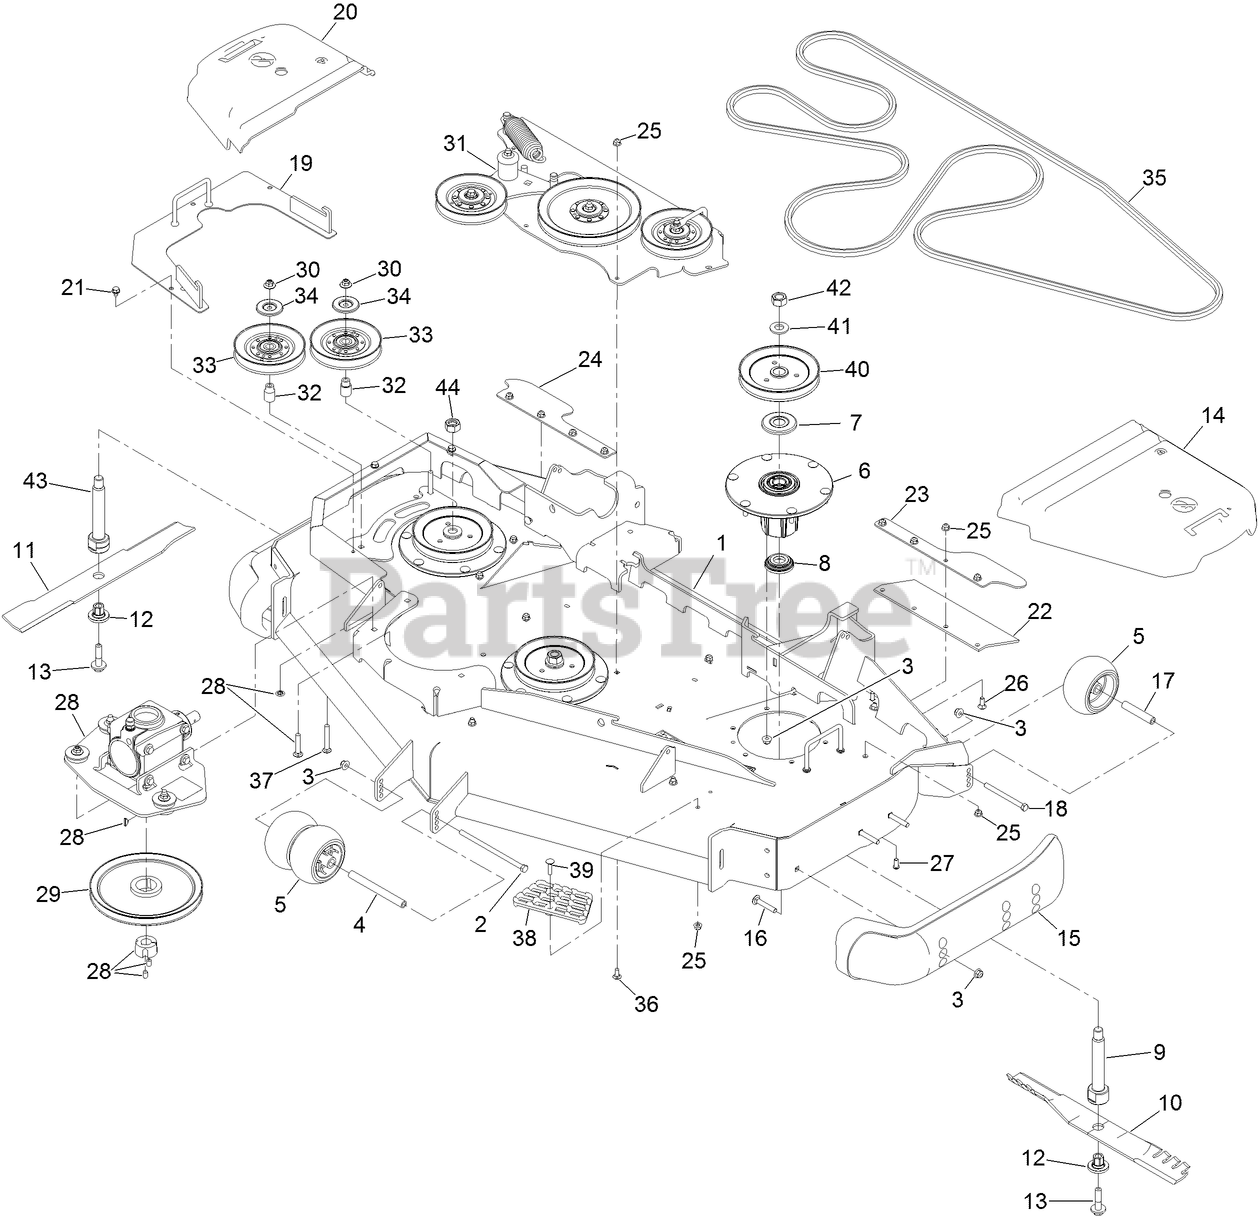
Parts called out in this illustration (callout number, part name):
1	DECK DECAL ASM
2	SCREW-HH
3	NUT-HF, NI
4	SPACER-WHEEL
5	ROLLER-SCALP, ANTI
6	SPINDLE ASM
7	GUARD-BEARING, TOP
8	GUARD-BOTTOM
9	SHAFT-SPINDLE
10	BLADE-20.50 ATOMIC
11	BLADE-20.50 CR LOW FLOW
12	BUSHING-HEX
13	SCREW-SEMS
14	COVER-BELT, LH
15	SKID-BUMPER, DECK
16	SCREW-CARR
17	TUBE-SPANNER
18	SCREW-HH
19	COVER-DRIVE REVERSE
20	COVER-BELT, RH
21	SCREW
22	GUARD-TIRE
23	SUPPORT-FLAP, OUTER (LH)
24	SUPPORT-FLAP, OUTER (RH)
25	NUT-HF, NI
26	SCREW-CARR
27	SCREW-HSBH
28	GEARBOX ASM
29	PULLEY
30	NUT-FLANGE, NI
31	IDLER MOUNT ASM
32	STANDOFF-IDLER
33	IDLER V
34	SHIELD-DUST
35	BELT-BB
36	SCREW-CARR
37	SCREW-CARR
38	STEP-DECK
39	SCREW-CARR
40	SHEAVE-BLADE DRIVE 6.50
41	WASHER
42	NUT-HEX
43	SHAFT-SPINDLE, INT. HEX LH THD
44	NUT-HEX,LH,LOCK
